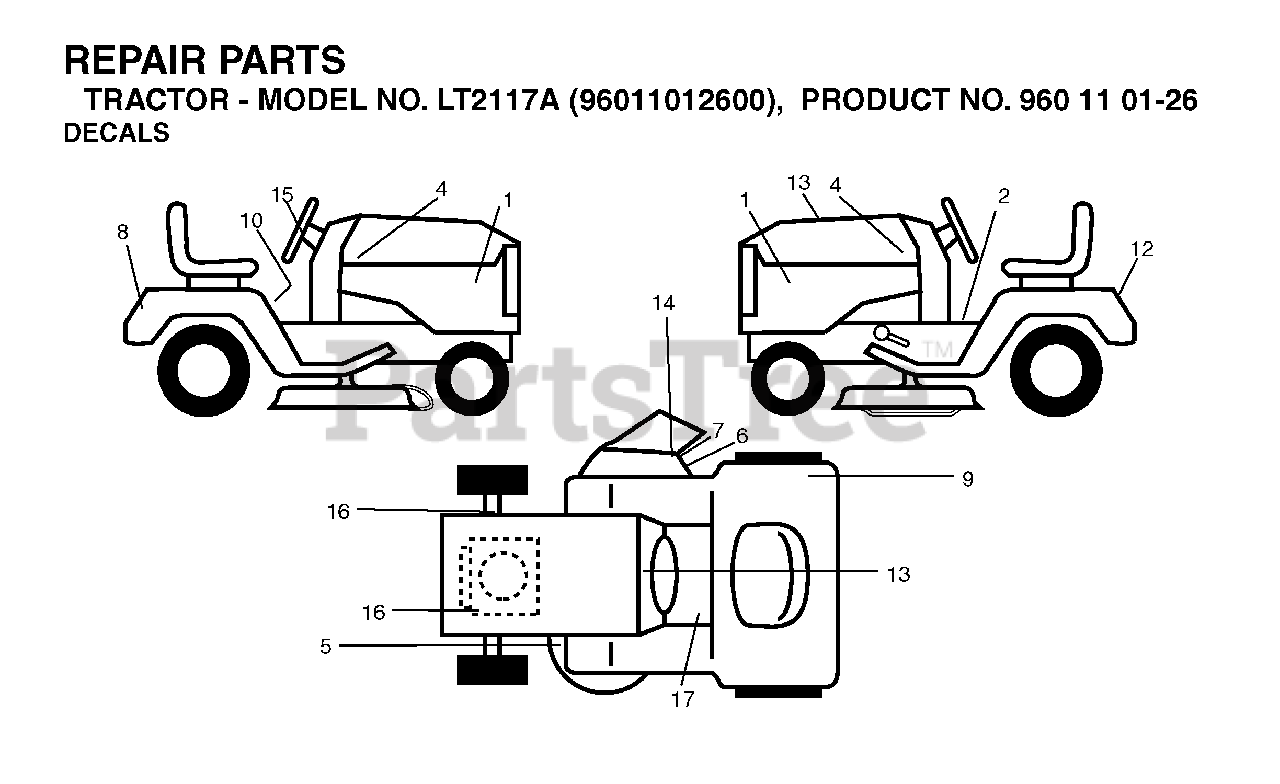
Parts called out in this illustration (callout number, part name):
2	DECAL PARK BRAKE
5	DECAL V BELT SCHEMATIC
6	DECAL, DEFLECT WARNING
7	DECAL.INTERNATIONL.CUTFINGER
11	DECAL BTRY SYMBOLS
14	DECAL DECK "B" 42"
